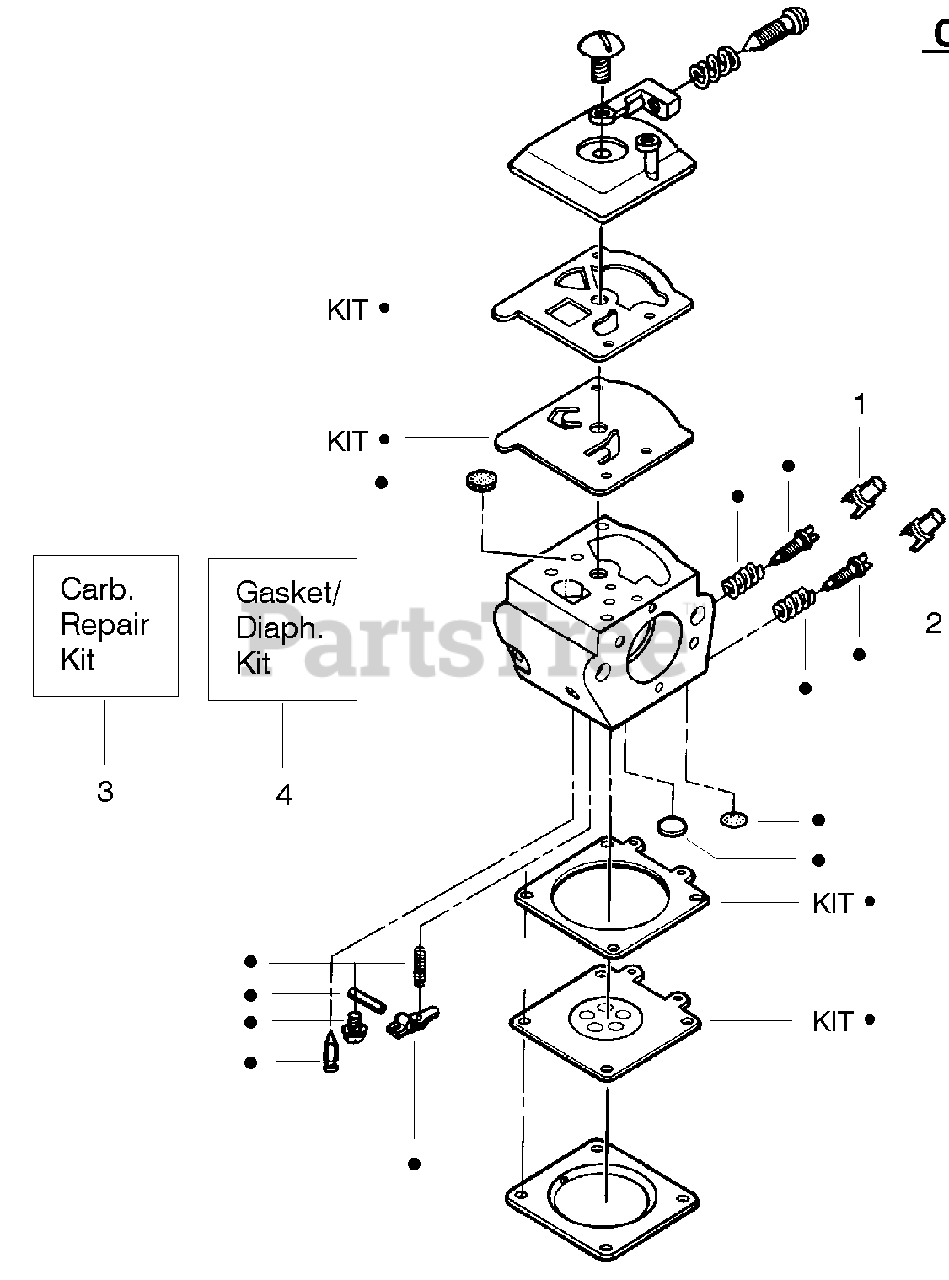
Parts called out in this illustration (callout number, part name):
1	Limiter Cap-High (brown)
2	Limiter Cap-Low (tan)
3	Carburetor Repair Kit ( • Indicates Contents)
4	Gasket/Diaphragm Kit (KIT=Indicates Contents)
